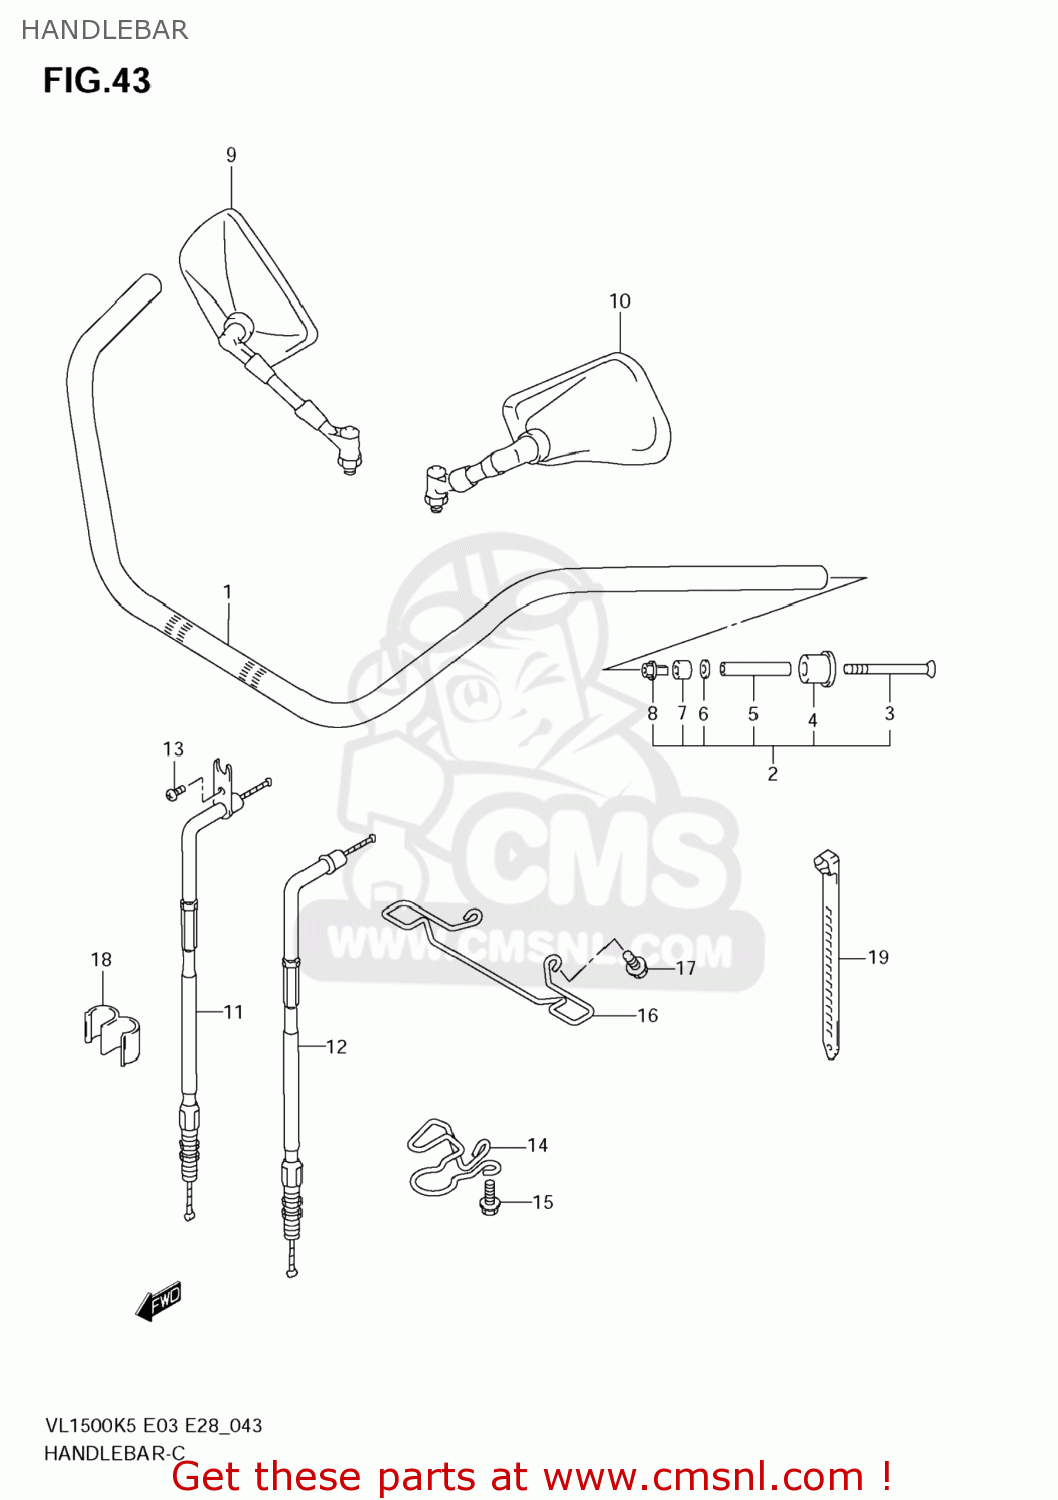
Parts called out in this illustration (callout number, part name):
1	HANDLEBAR
2	BALANCER SET,HANDLEBAR
3	SCREW(6X127)
4	EXPANDER,HANDLE BALANCER NO.2
5	SPACER,EXPANDER
6	WASHER(6.5X16X4)
7	EXPANDER,HANDLE BALANCER
8	NUT,HANDLE BALANCER
9	MIRROR ASSY,RE
10	MIRROR ASSY,RE
11	CABLE ASSY,THROTTLE NO.1
12	CABLE ASSY,THROTTLE NO.2
13	SCREW(5X10)
14	GUIDE,THROTTLE CABLE
15	BOLT
16	GUIDE,CABLE
17	BOLT
18	CLIP
19	CLAMP(L:95)
